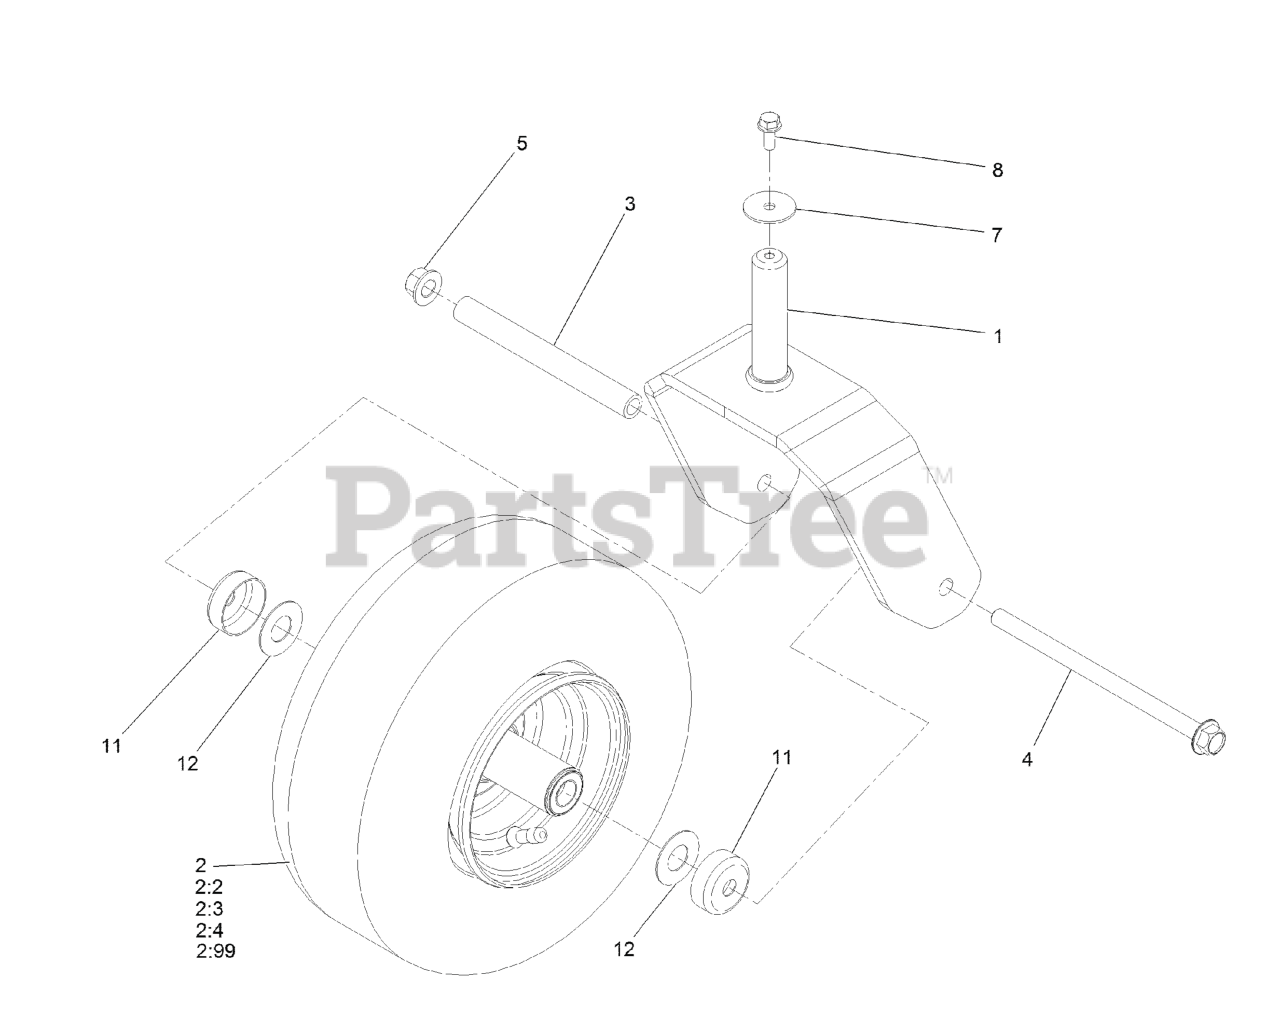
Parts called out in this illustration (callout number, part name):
2	TIRE AND WHEEL ASM
2:3	Stem-Valve
2:4	BEARING
3	SPANNER-WHEEL
4	SCREW-HHF
5	Nut-Lock 1/2-13
7	WASHER-FLAT
8	SCREW-HHF
11	GUARD-SEAL
